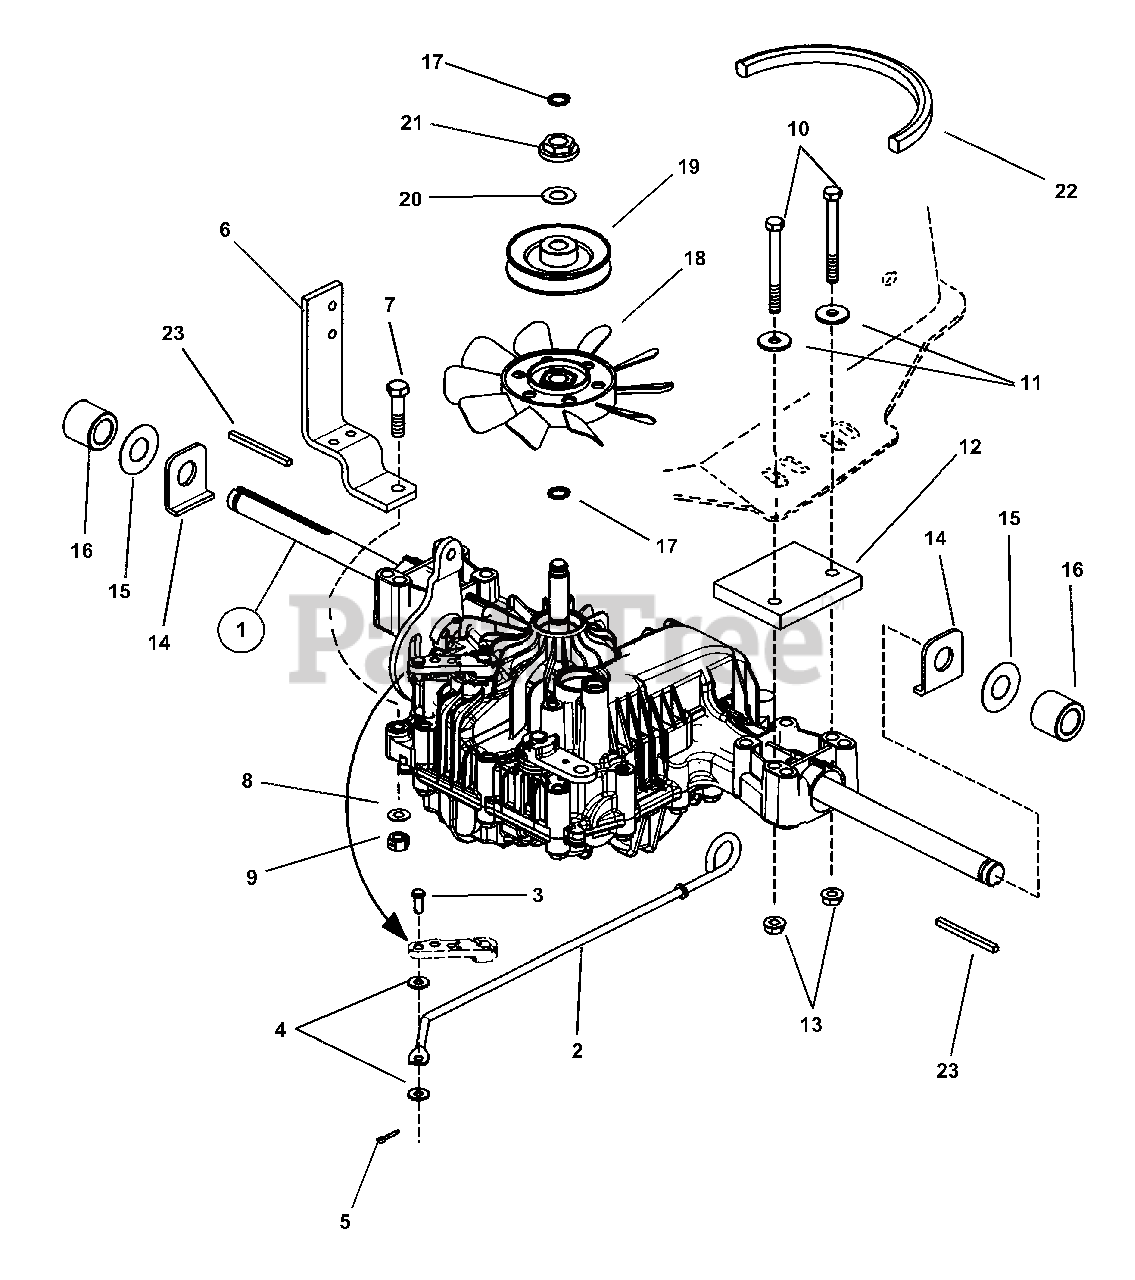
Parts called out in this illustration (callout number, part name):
1	ASSEMBLY, Transaxle, Tuff Torq (Models: LT160H42GBV & LT160H42GBV2)
2	ROD, Roll Release (K46)
3	PIN, Clevis 1/4" x 5/8"
4	WASHER, 1/4 x 5/8 x 1/16" Flat
5	PIN, 3/32" x 1/2" Cotter
6	BRACKET, Torque
7	SCREW, 3/8-16 x 1-1/2" Hex Head Cap, Grade 5
8	WASHER, 5/16 x 11/16 x 1/16", Grade 5
9	NUT, 3/8-16 Hex Center Lock
10	SCREW, 5/16-18 x 3-1/4" Hex Head Cap, Grade 5
11	WASHER, 5/16" Flat
12	SPACER, Hydro Axle- K46
13	NUT, 5/16-18 Hex Flange Lock Grade 5
14	WASHER, Axle
15	WASHER, Thrust
16	SPACER, Axle
19	PULLEY, 4" Diameter (Vendor # 1A6460-25333)
22	BELT, Traction Drive (HA Section, 96.60 Effective Length)
23	KEY, 3/16" Square x 2-3/16" long
